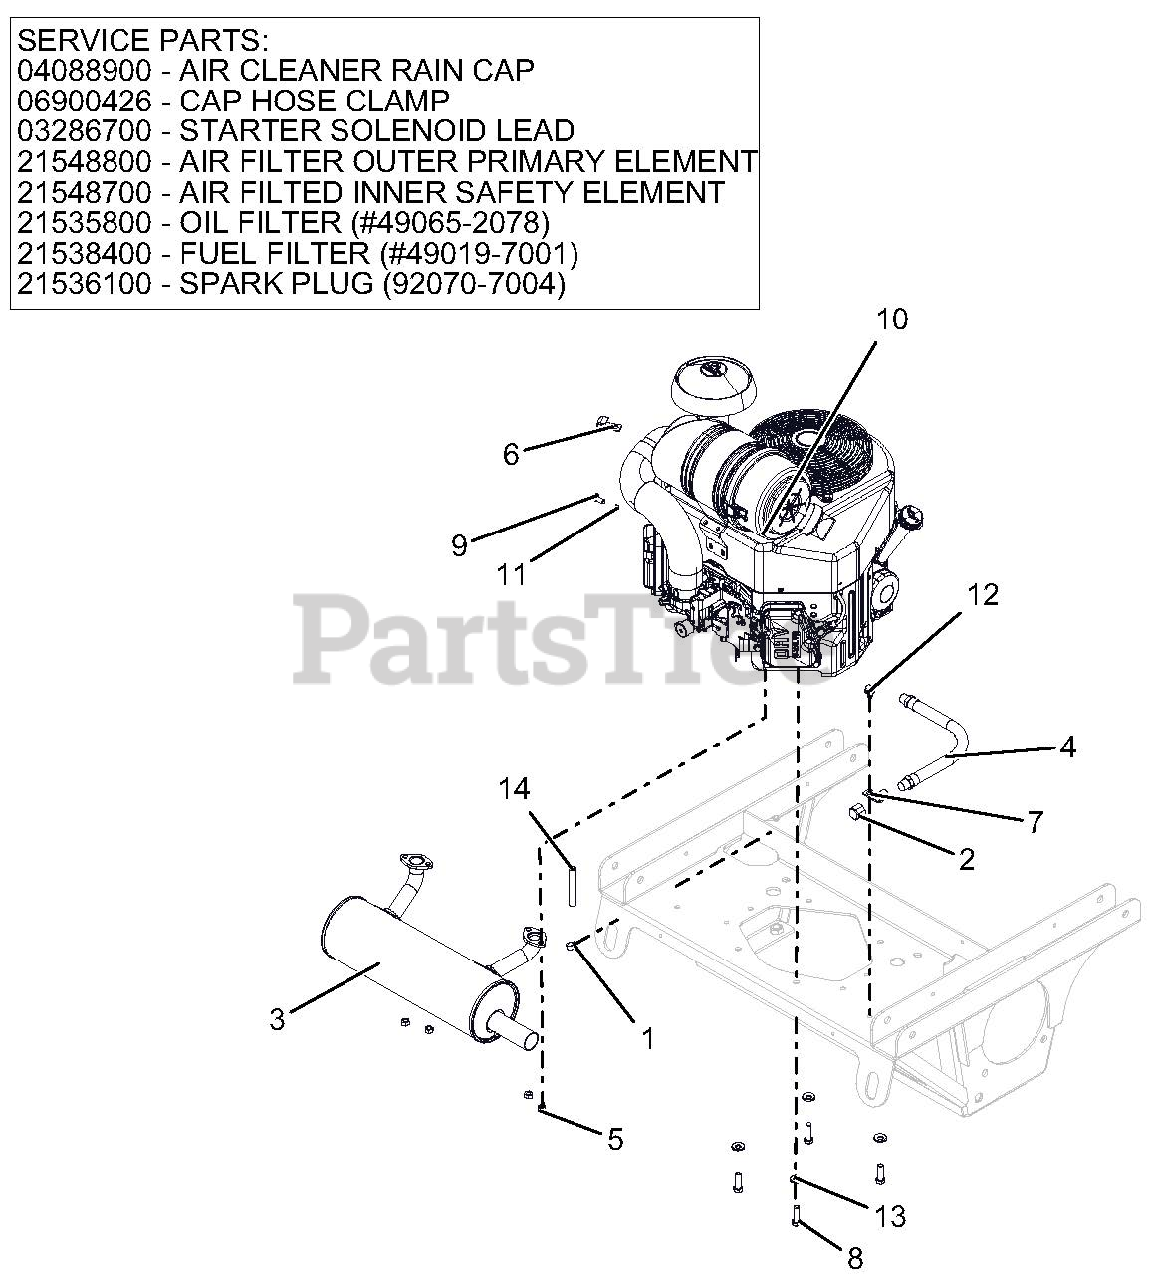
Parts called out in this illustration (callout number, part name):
1	CLAMP, FUEL LINE
2	PIPE, CAP 3/8 NPT FEMALE
3	MUFFLER, KAWASAKI FX24/26 HP
4	HOSE, HYD .38-11-OK M6N0-M6N0
5	NUT-LK-TOP M8-1.25 YWZC
6	CLAMP, J
8	BLT-HEX .38-16X1.25 GR5 YWZC NYTORQ
9	@BLT-HEX M8-1.25X20 YWZC
10	ENGINE, KAWASAKI FX730
11	WSHR-LK .31X.078 REG YWZC
12	SCR-TAP .38-16X.50 HWH TR YWZ
13	WSHR, 3/8" SPRING DISC
14	.25 LOW-PERM GAS HOSE 3.00" LG - VALVE TO KAW FX730
15	AIR CLEANER RAIN CAP
16	CAP HOSE CLAMP
17	STARTER SOLENOID LEAD
18	AIR FILTER OUTER PRIMARY ELEMENT
19	AIR FILTED INNER SAFETY ELEMENT
20	OIL FILTER (#49065-2078)
21	FUEL FILTER (#49019-7001)
22	SPARK PLUG (92070-7004)
